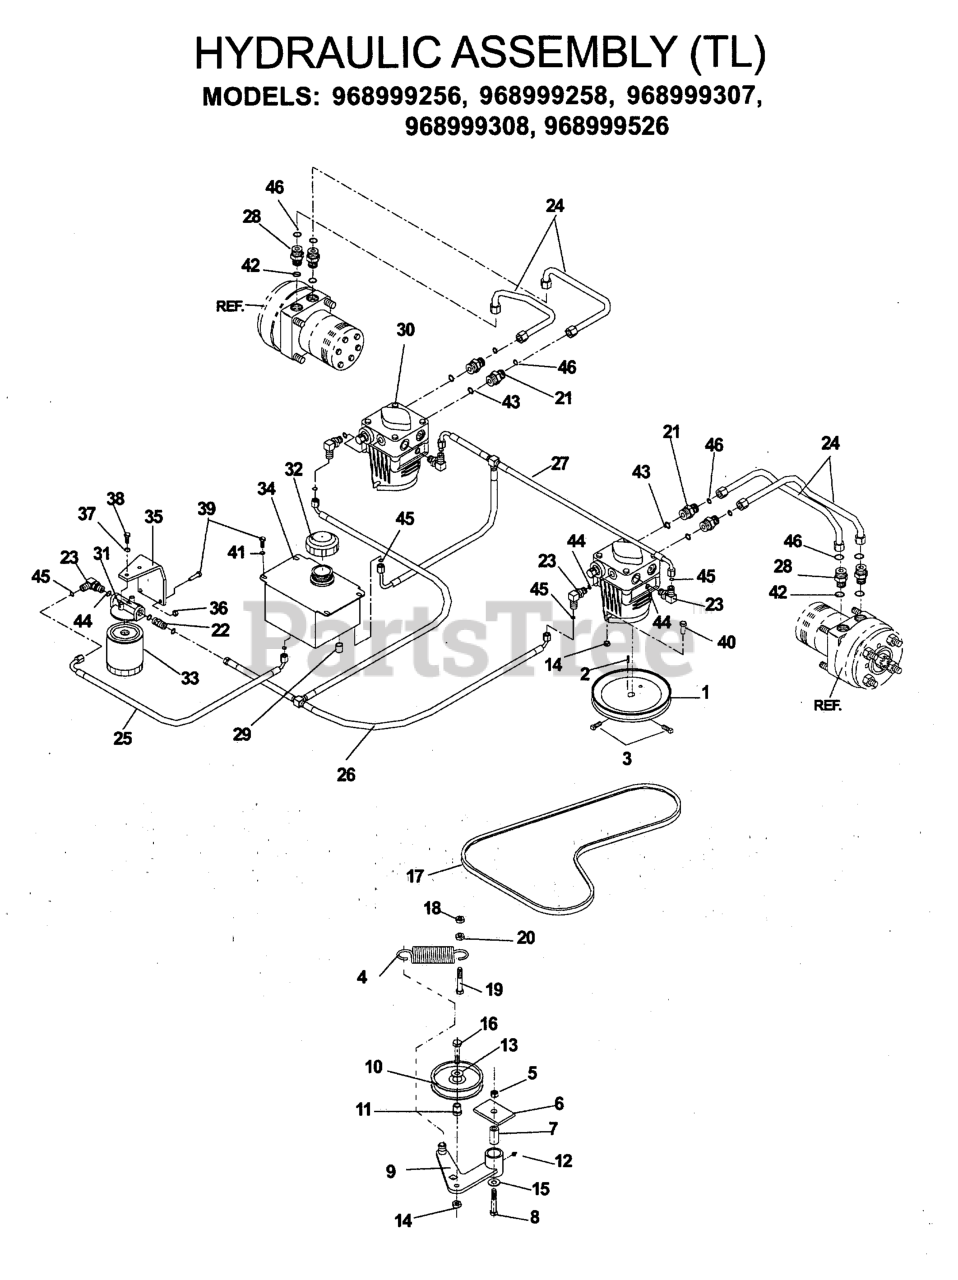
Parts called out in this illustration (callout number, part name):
2	KEY 5 MM SQ X 25 MM
3	SCREW 5/16C X 5/8 SQ HEAD
5	NUT 1/2-13 HEX NYLOC ZD
7	PIVOT BUSHING
8	HCS 1/2C X 3 1/4
9	IDLER ARM WLDT
10	IDLER PULLEY
11	BUSHING, IDLER FLANGE
12	ZERK
13	WASHER 3/8 FLAT
14	NUT 3/8C CENTERBLOCK
15	WASHER 1/2 FLAT
16	HCS 3/8-16 X 1 3/4 GR5
17	PUMP BELT
18	NUT 3/8-16 NYLOC
19	HCS 3/8C X 2
20	NUT 3/8C WHIZ
21	FITTING, STRAIGHT F6400-8-8-0
22	HYDRAULIC FITTING
23	ELBOW, F6801-6-6-0 90 DEGREE
24	HYDRAULIC HOSE
26	T-ASSEMBLY
29	NUT 9/16-18 JIC CAP
30	10CC PUMP W/RTN'S
31	FILTER HEAD
32	HYDRAULIC CAP
33	HYDRAULIC OIL FILTER
35	OIL FILTER BRKT
36	NUT.1/4-20.HEX.NYLOC.ZD
37	LOCKWASHER 1/4"
38	HCS 1/4C X 5/8
39	HCS 1/4C X 3/4 HCS
40	4CS 3/8C X 1 SERRATED HEAD
41	WASHER 1/4 FLAT
